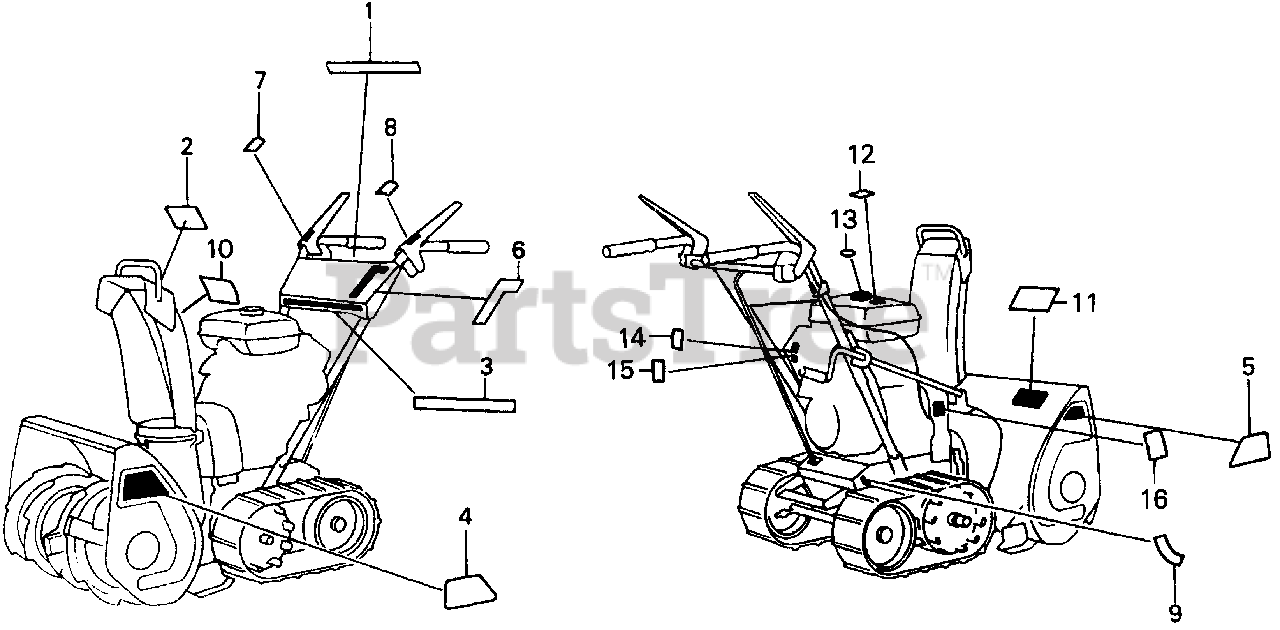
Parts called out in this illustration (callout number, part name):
1	MARK, CONTROL PANEL (A)
2	LABEL, WARNING (ENGLISH)
3	EMBLEM, CONTROL PANEL
4	EMBLEM, L. SIDE COVER
5	EMBLEM, R. SIDE COVER
6	MARK, CHANGE
7	MARK, AUGER CLUTCH
8	MARK, CLUTCH
8	MARK, CLUTCH (NOT AVAILABLE)
9	MARK, HEIGHT ADJUSTING
10	MARK, HOUSING DANGER (ENGLISH)
11	MARK, DISCHARGE DANGER (ENGLISH)
12	MARK, CAUTION (EXTERNAL)
13	MARK, FUEL CAUTION
14	MARK, CHOKE (A)
15	MARK, THROTTLE
16	MARK, OIL CAUTION
